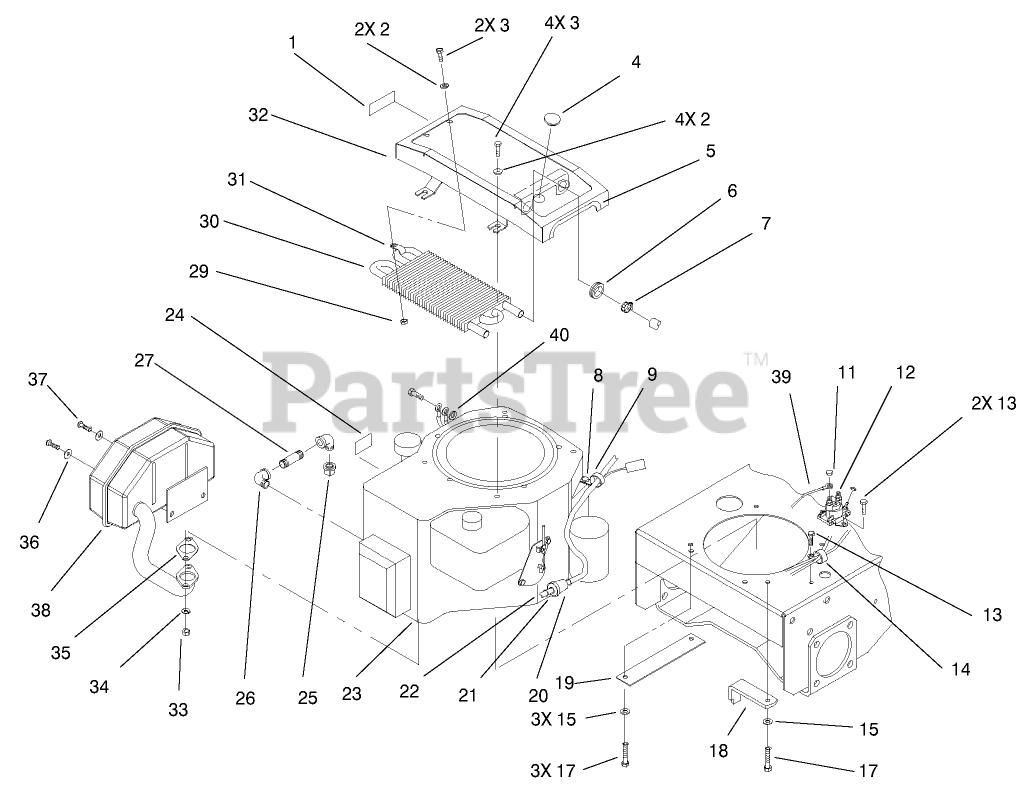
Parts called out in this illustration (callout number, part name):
1	DECAL-SHUT OFF, FUEL
2	WASHER-FLAT
3	SCREW-HH
4	PLUG-PLASTIC
5	TRIM-MOUNT, COOLER
6	GROMMET
7	CLAMP-HOSE
8	SCREW-SHWH
9	CLAMP-R
11	NUT-KEPS
12	SOLENOID
13	SCREW-HWH
14	CLAMP-R
15	WASHER-PLAIN
17	SCREW-HH
18	RETAINER-CLUTCH
19	COVER-PULLEY
20	FILTER-FUEL
21	CLAMP-HOSE
22	HOSE-FUEL
23	Engine-15 HP Kohler
24	DECAL-SURFACE, HOT
25	CAP-PIPE
26	ELBOW-STREET, 90 DEG
27	NIPPLE-PIPE
29	NUT-LOCK, NI
30	Cooler-Oil
31	CLAMP-R
32	MOUNT-COOLER
33	NUT-MUFFLER
34	WASHER-LOCK
35	GASKET-EXHAUST
36	WASHER-FLAT
37	SCREW-MUFFLER
38	MUFFLER
39	WIRE ASM
40	WASHER-LOCK
